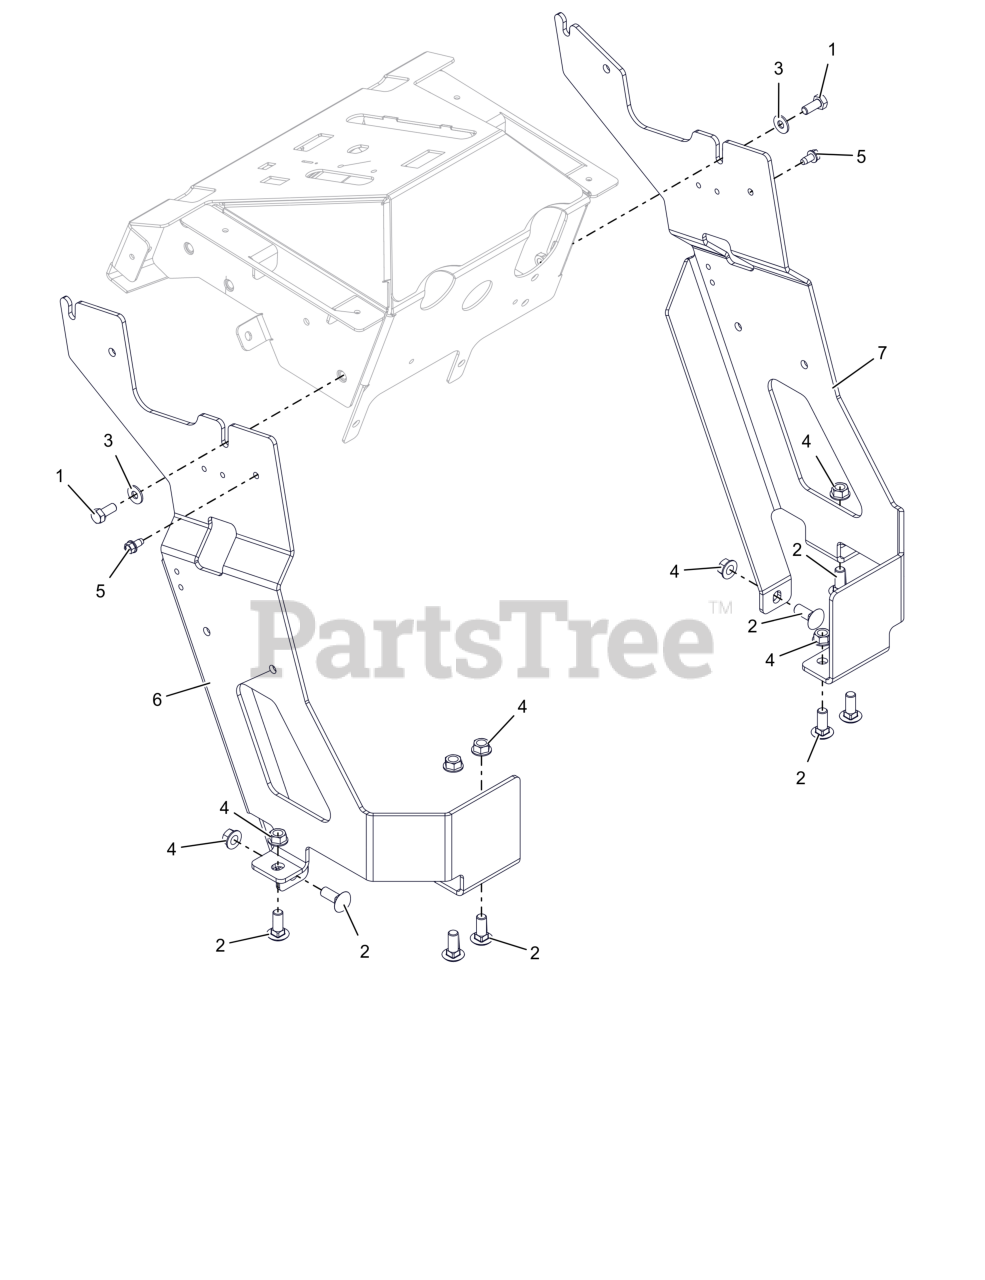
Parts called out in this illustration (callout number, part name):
1	BLT,HEX .31-18X.75 G5 ZCC
2	BLT, RHSN .38-16X1.00 G5 ZCC
3	WSHR, FLT .312X.734X.065 ZCC
4	NUT-LK-CTR-FLG .375-16 GF ZCC
5	SCR-TAP .25-20X.50 HWH ZCC
6	SIDE, RH TOWER (BLACK)
7	SIDE, LH TOWER (BLACK)
